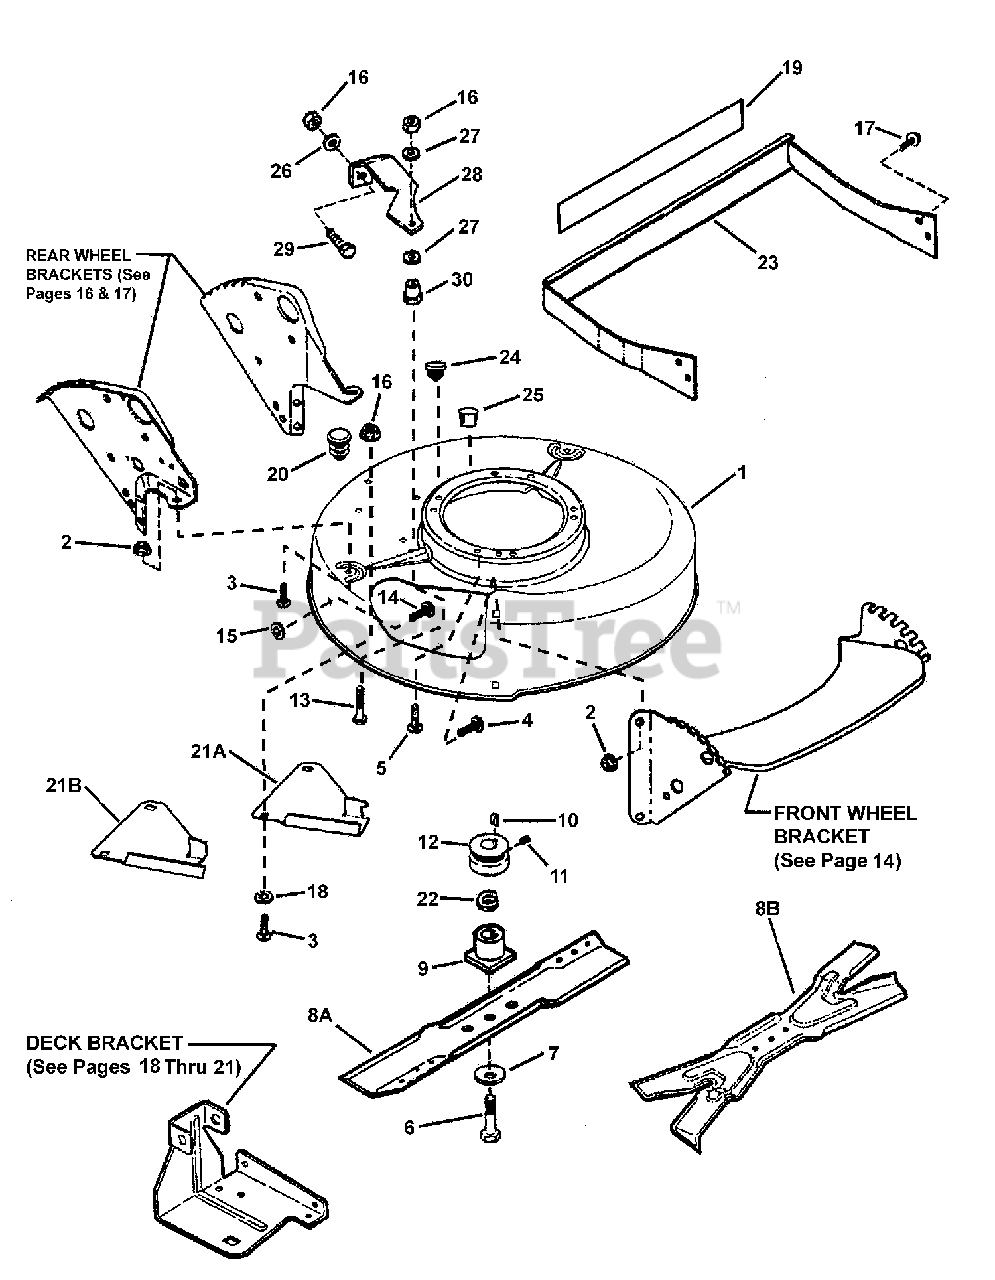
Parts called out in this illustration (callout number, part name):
1	DECK, 21" Mower
2	NUT, 5/16-18 Hex Flange Lock, GR5
3	BOLT, 5/16-18 x 1/2" Short Neck Carriage GR5
4	BOLT, 5/16-18 x 1-1/8" Short Neck Carriage GR5
5	SCREW, 3/8-16 x 1" Self-Tap
6	SCREW, 3/8-24 x 1-3/4 Hex Head Cap GR5
7	WASHER, 3/8" I.D. Cone
8A	BLADE, Cutter (Mulching)
8B	BLADE, 21" Ninja
9	HUB, Blade Drive 25mm
10	KEY, Hi-Pro #HP506 (Briggs engine)
11	SCREW, 5/16-18 x 5/16" Hex Socket Set
12	PULLEY, Engine Drive (25mm x 2-1/8" O.D.)
13	BOLT, 5/16-18 x 2-1/4" Hex Flange Lock
14	BOLT, 5/16-18 x 3/4" Short Neck Carriage GR5
15	RETAINER, 5/16" Bolt
16	NUT, 5/16-18 Hex Flange Lock, GR5
17	SCREW, 1/4-20 x 1/2" Hex Washer Self-Tap
18	WASHER, 7/16" Flat
19	DECAL, Operator Safety
20	PLUG, Hole Polyethylene
21A	BAFFLE, Belt
21B	BAFFLE, Belt
22	SPACER, Blade Hub
23	WELDMENT, Fender
24	PLUG, 5/16" Square Hole
25	PLUG, 5/16" Round Hole
26	WASHER, 5/16" Flat
27	WASHER, 7/16" Flat
28	COVER, Belt
29	SCREW, 5/16-18 x 1/2" Hex Head Cap, GR5
30	BUSHING
